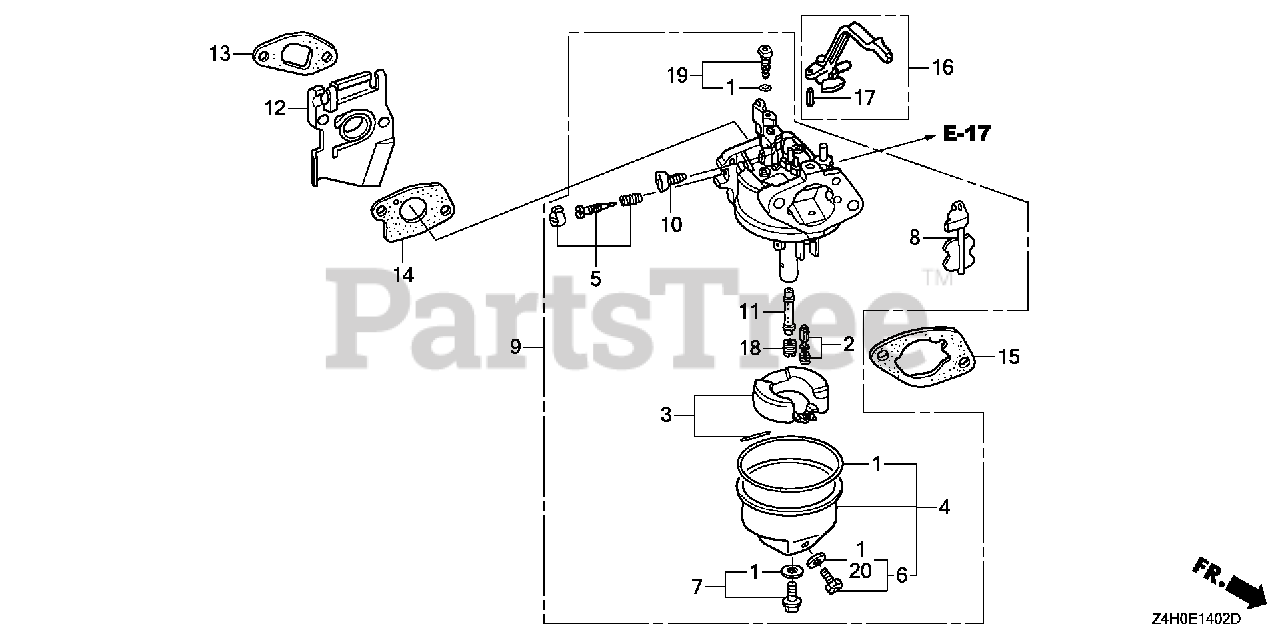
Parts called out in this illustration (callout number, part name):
1	GASKET SET (CARBURETOR NO.)
2	VALVE SET, FLOAT (CARBURETOR NO.) (SEAT NOT INCLUDED)
3	FLOAT SET
4	CHAMBER SET, FLOAT (CARBURETOR NO.)
5	SCREW SET (Honda Code 4219879). (CARBURETOR NO.)
6	SCREW SET, DRAIN (Honda Code 1672187). (CARBURETOR NO.)
7	SCREW SET
8	CHOKE SET
9	CARBURETOR ASSY. (BE62D B)
9	CARBURETOR ASSY. (BE62G A)
10	SCREW, THROTTLE STOP
11	NOZZLE, MAIN
12	INSULATOR, CARBURETOR
13	GASKET, INSULATOR
14	GASKET, CARBURETOR
15	GASKET, AIR CLEANER
16	LEVER, CHOKE
17	PIN, SPRING (2X12)
18	JET, MAIN (#58) Use from Engine SN BE30B E.
18	JET, MAIN (#60)
18	JET, MAIN (#62)
19	JET SET, PILOT (#35)
20	WASHER, PLAIN (6.2X10.7 DRAIN) (CARBURETOR NO.)
